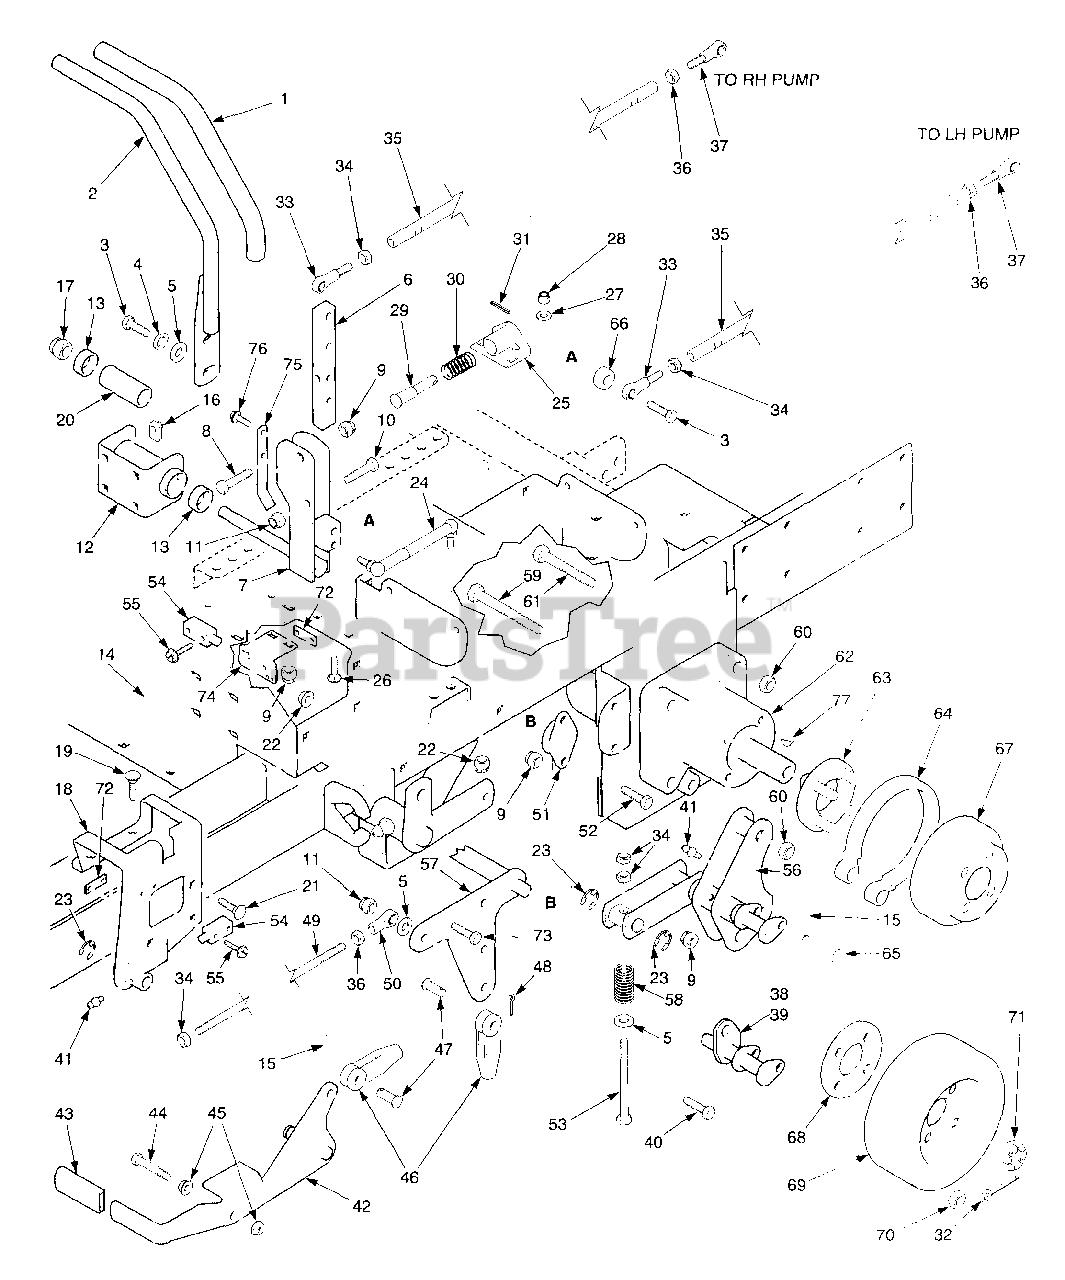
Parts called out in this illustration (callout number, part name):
1	Grip, Handle Bar
2	Handle Bar
3	Bolt, Hex Head 3/8-16 x 1-1/4"
4	Lockwasher, 3/8"
5	Flatwasher. 3/8" (.391 x .938 x .105)
6	Bar, Control Lever
7	Control Lever
8	Bolt, Hex Head 5/16-18 x 2"
9	Nut, Hex Elastic Stop 5/16-18
10	Bolt, Hex Head 3/8-16 x 2"
11	Nut, Hex Elastic Stop
12	Bracket, Control
13	Ball Bearings, Neutral Return
14	Bolt, Hex Head 5/16-18 x 1-1/4"
15	Pin, Rue Cotter 3/8 DIA
16	U-Nut, 5/16-18
17	Nut, Hex Elastic Stop 5/8-11
18	Bracket, Control Lever LH
19	Bolt, Carriage 5/16-18 x 1"
20	Spacer, Bearing
21	Bolt, Carriage 5/16-18 x 3/4"
22	Nut, Hex Serrated Flange 5/16-18
23	Ring, Retaining 5/8" External "E"
24	Gas Damper
25	Bracket, Neutral Return
26	Bolt, Carriage 1/4-20 x 3/4"
27	Flatwasher, 1/4" (.312 x .750 x .065)
28	Nut, Hex Elastic Stop 1/4-20
29	Pin, Retaining Spring
30	Spring
31	Roll Pin, Spring 5/32 x 3/4"
32	Pin, Cotter 9/16 x 1-1/2"
33	Rod End, Male 3/8-24 RH THD.
34	Nut, 3/8-24 RH THD.
35	Tube, Control Link
36	Nut, Hex 3/8-24 LH THD.
37	Rod End, Male 3/8-24 LH THD.
38	Brake Linkage Weldment LH
39	Brake Linkage Weldment RH
40	Bolt, Hex Head 5/16-18 x 1"
41	Grease Fitting
42	Lever, Parking Brake
43	Grip, Parking Brake
44	Bolt, Hex Head 3/8-16 x 2-3/4"
45	Nut, Hex Serrated Flange 3/8-16
46	Clevis, Traction Control
47	Pin, Clevis 3/8-16 x 1-1/16"
48	Pin, Cotter 3/32 x .75
49	Rod, Parking Brake
50	Rod End, LH THD.
51	Bushing, Self Align
52	Bolt, Hex Head 5/16-18 x 3/4"
53	Bolt, Hex Head 3/8-24 x 5-1/4", 2-3/4" Thread
54	Switch
55	Screw, Hex SLTD WSHR Head #10-32 x 3/4"
56	Brake Linkage, LH
57	Bellcrank, Brake Actuator
58	Spring
59	Bolt, Hex Head 1/2-13 x 3-1/2"
60	Locknut, Hex 1/2-13 Center Lock
61	Bolt, Hex Head 1/2-13 x 2-1/2"
62	Wheel Motor, Ross
63	Wheel Hub Assembly
64	Brake Band Assembly
65	Pin, Clevis 3/8" Dia. x 2"
66	Spacer
67	Brake Drum
68	Spacer, Wheel
69	Wheel Assembly 24 x 12-12 Turf Master
70	Lug Nut, 1/2-20
71	Nut, Hex Castle
72	Plate, Threaded
73	Bolt, Hex Head 3/8-16 x 1-1/2"
74	Bracket, Switch Mounting
75	Bracket, Switch Actuator
76	Bolt, Hex Serrated Flange 5/16-18 x 3/4"
77	Key, Woodruff 5/16 x 1"
